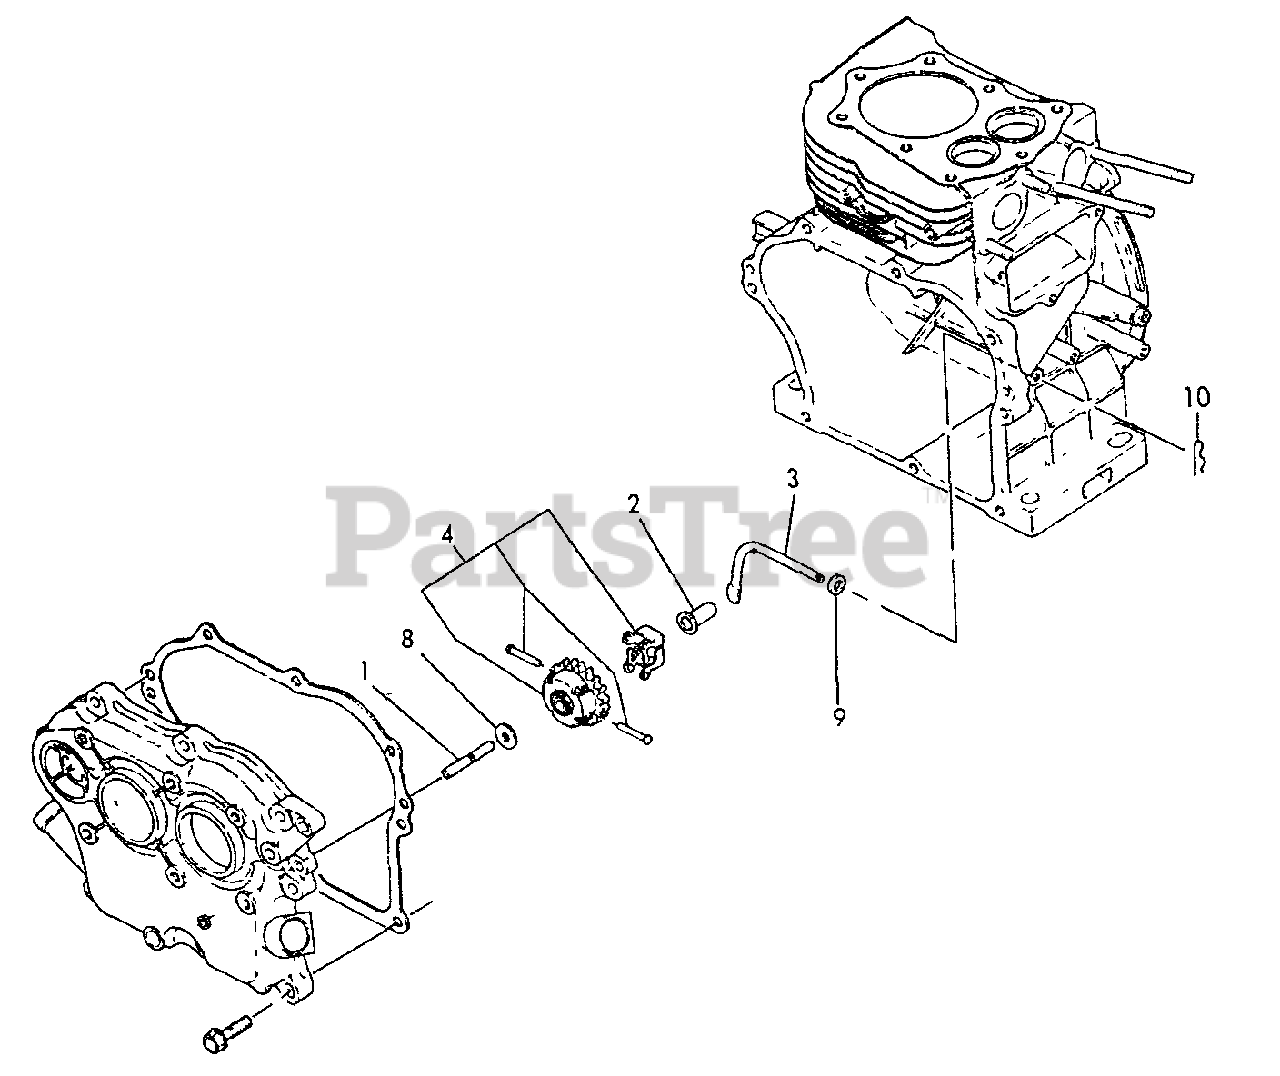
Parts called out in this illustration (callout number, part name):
1	SHAFT, GOVERNOR
2	SPINDLE, GOVERNOR
3	YOKE, GOVERNOR
4	GOVERNOR GEAR ASSY
8	WASHER - 6
9	WASHER - 6
10	PIN - 6 -- SNAP
